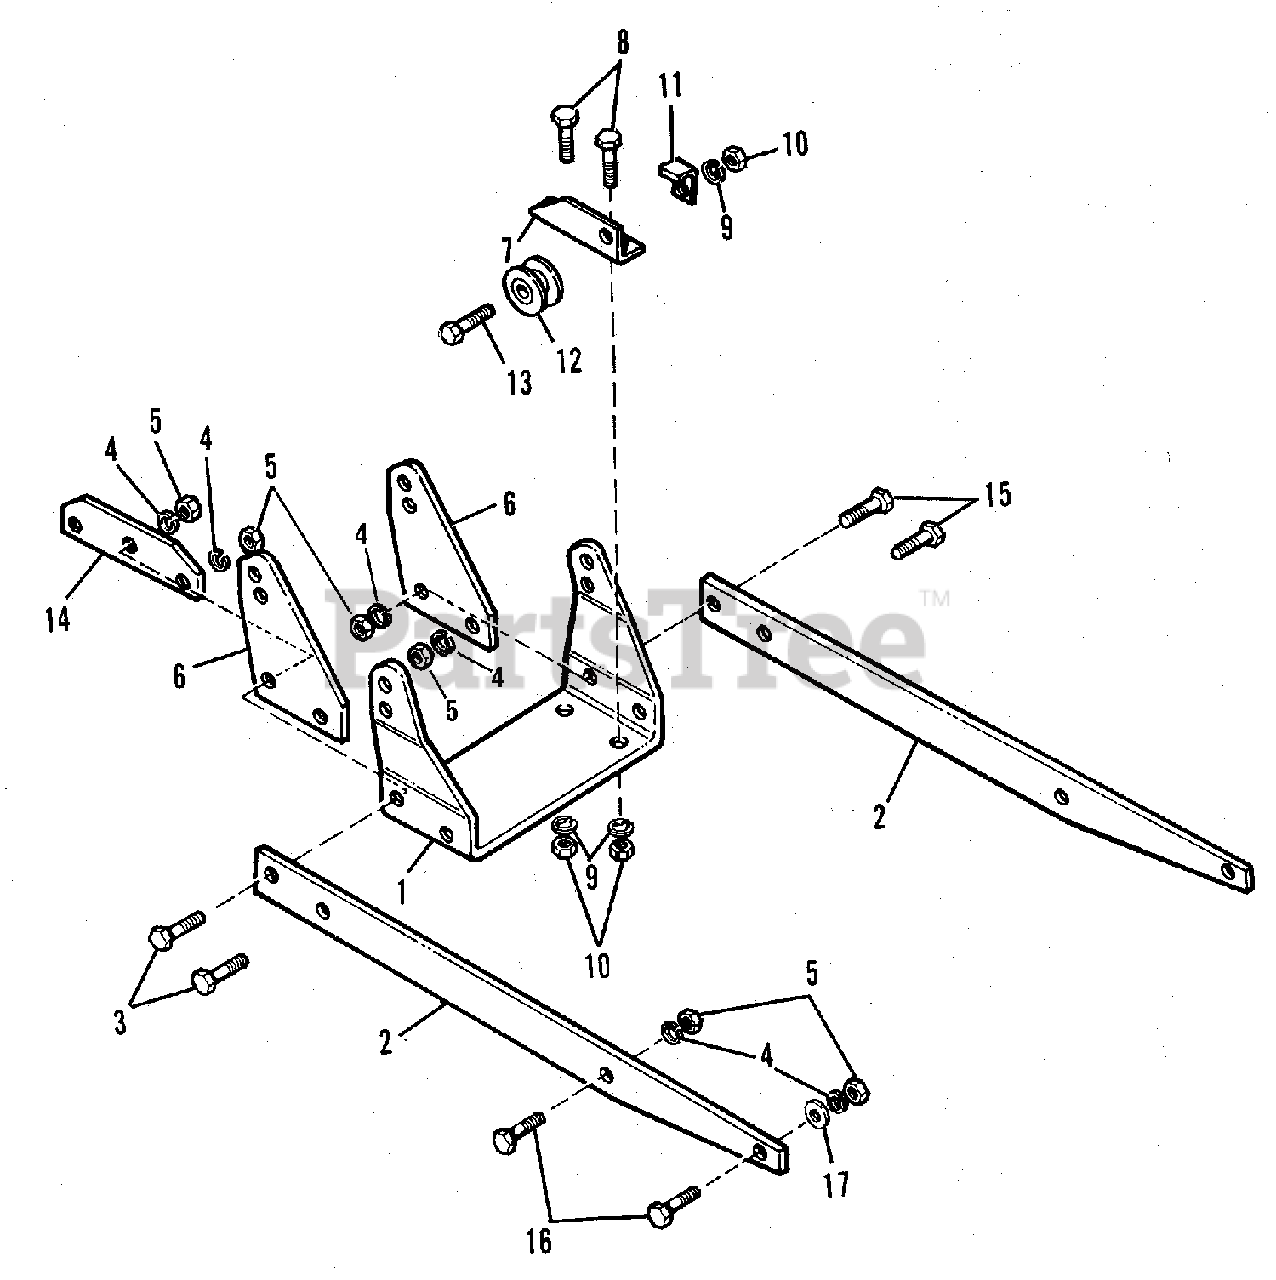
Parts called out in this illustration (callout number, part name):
1	BRACKET, Pivot
2	FLATBAR, Attaching
3	CAPSCREW, Hex Head, 7/16-14 x 1-3/4
4	LOCKWASHER, 7/16
5	NUT, Hex, 7/16-14
6	BRACKET, Support, Pivot
7	SUPPORT, Idler
8	CAPSCREW, Hex Head, 3/8-16 X 1
9	LOCKWASHER, 3/8
10	NUT, Hex, 3/8-16
11	GUIDE, Belt
12	PULLEY, Idler
13	CAPSCREW, Hex Head, 3/8-16 x 1-3/4
14	BRACKET, Lift Rod
15	CAPSCREW, Hex Head, 7/16-18 x 1-1/2
16	CAPSCREW, Hex Head, 7/16-18 x 1-1/4
17	WASHER, 7/16
